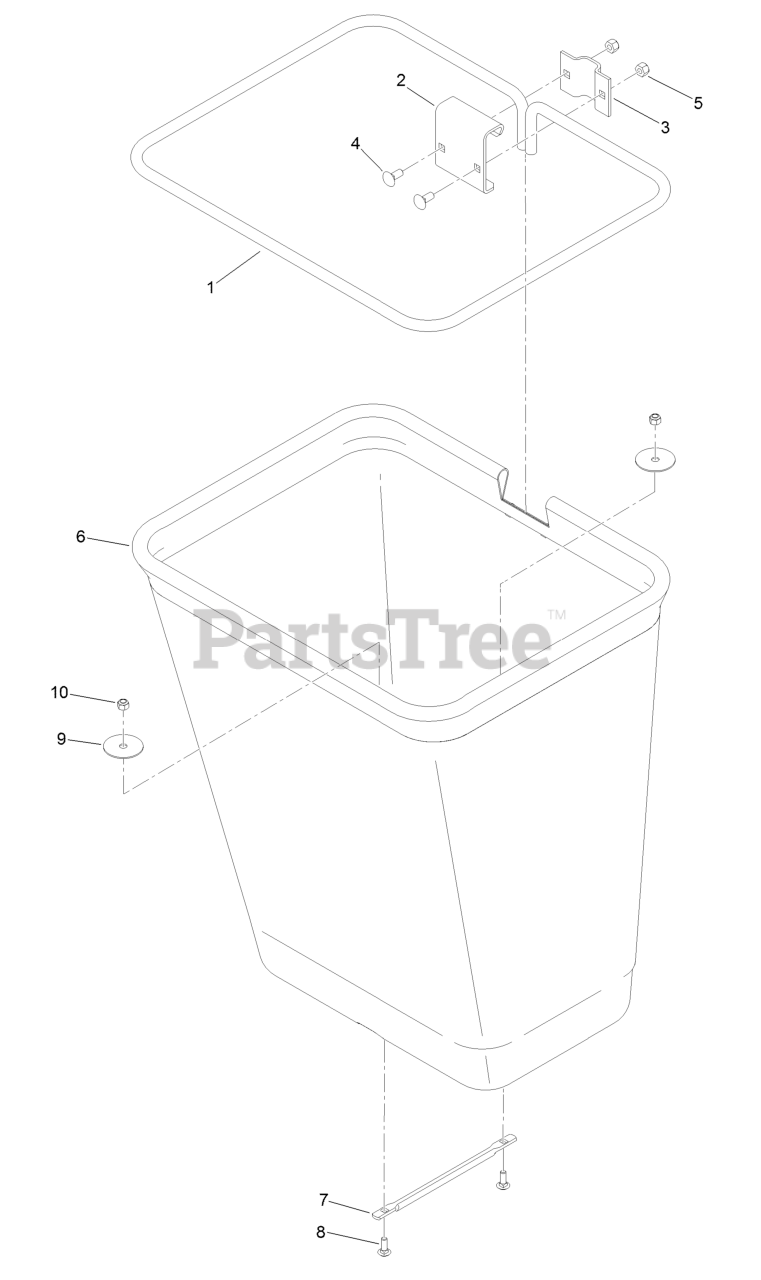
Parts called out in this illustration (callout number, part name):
1	Frame-Bag
2	Hanger-Bag
4	Bolt-CARR
5	Nut-Lock, NI
6	Bag ASM
7	Handle-Bag
8	Bolt-CARR
10	Nut-Lock, NI
